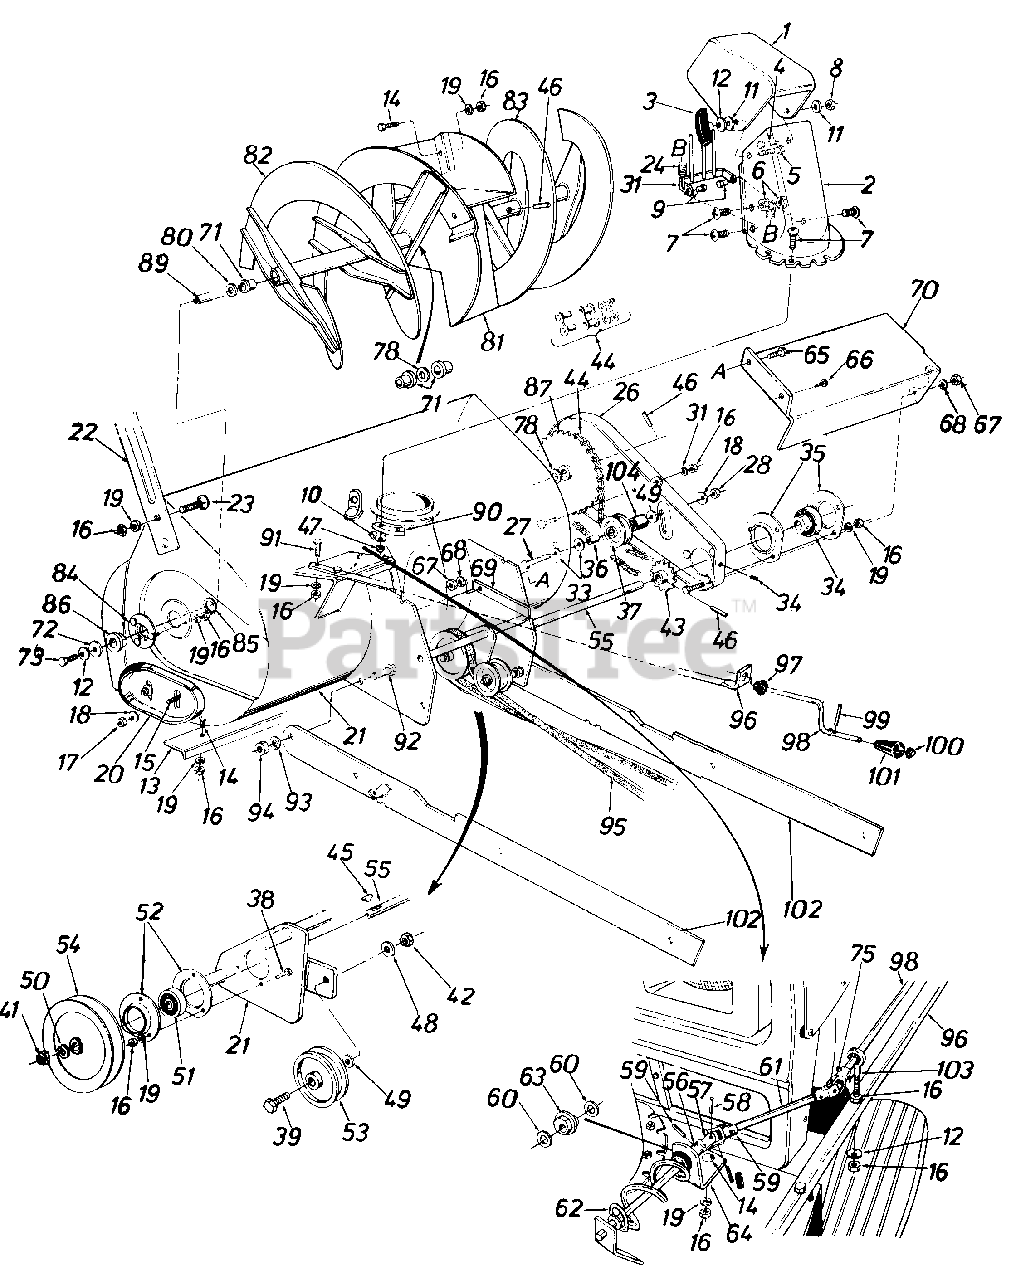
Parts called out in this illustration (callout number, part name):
1	Upper Chute
2	Lower Chute
3	Knob Handle Ass'y.
4	Truss Mach. Scr. 5/16-18 x .75" 4.
5	Carriage Bolt 5/16-18 x 1.0"*
6	Hex Cent. L-Nut 5/16-18 Thd.
7	Truss Mach. Scr. 1/4-20 x .75" 4.
8	Hex Cent. L-Nut 5/16-18 Thd.
9	Shld. Nut 1/4-20 Thd.
10	Fl.-Wash. 1/4" I.D.
11	Fl.-Wash. .344" I.D. x 1.125"
12	Bell. Wash. .345" I.D. x .88"
14	Carriage Bolt 5/16-18 x .62"
15	Carriage Bolt 3/8-16 x .62"*
16	Hex Nut 5/16-18 Thd.*
17	Hex Jam Nut 3/8-16 Thd.
18	Bell. Wash. .40 I.D. x .88"
19	L.-Wash. 5/16" I.D.*
20	Slide Shoe
21	Spiral Hsg. Ass'y.-36"
22	Guide Blade
23	Carriage Bolt 5/16-18 x .62"*
24	Extension Spring
26	Chain Guard Ass'y.
27	Hex Bolt 3/8-16 x 2.00 4.*
28	Hex Inst.-Nut 3/8-16 Thd.
33	Fl.-Wash. .385" I.D. x .87" O.D.
34	Ball Brg. .75" I.D.
35	Flangette
36	Spacer .375" I.D. x .60" O.D.
37	Fl.-ldlere w/Flanges 1.875
38	Hex Sems Bolt 5/18 x .75" Lg.
39	Hex Bolt 3/8-16 x 1.75" 4.*
41	Hex Jam Nut 3/4-10 Thd.
42	Hex Jam Nut 3/8-16 Thd.
43	Sprocket Ass'y. 14 Teeth
44	#420 Chain x 1/2" Pitch 77 Links
45	#61 Hi-Pro-Key 3/16 x 5/8"
46	Spring Pin Spir. 5/16" Dia. x 1.75" 4
47	Hex L-Nut 1/4-20 Thd.
48	L.-Wash. 3/8" I.D.*
49	Fl.-Wash. .406" I.D. x 1.25"
50	Spring L.-Wash. 3/4" I.D.
51	Self-Aligning Brg.
52	Flangette
53	Ider Pulley
54	5/8 V-Pulley .75" I.D. x 6"
55	Drive Shaft Ass'y. - N
56	Joint Brkt. Ass'y.
57	Joint Block
58	Oval Head Rivet
59	Spiral Pin 1/8" Dia.
60	Fl.-Wash. .385" I.D. x .62"
61	Chute Crank Ext. Rod
62	Chute Crank Ass'y. R.H.
63	Plastic Bushing .380" I.D.
64	Chute Crank Brkt.
65	Hex Bolt 1/4-20 x .62" Lg.*
66	Hex Wash. S-Tap Scr. 1/4-20 x .50" 4
67	Hex Nut 1/4-20 Thd.*
68	L.-Wash. 1/4" I.D.*
69	Belt Cover
70	Drive Shaft Cover
71	Plastic Bushing
72	Washer .39" I.D. x 1.75" O.D.
73	Hex Bolt 5/16-18 x .88" Spec.
75	Cotter Pin 3/32" Dia.
78	Fl.-Wash. 1.03" I.D. x 1.62"
80	Fl.-Wash. 1.0" x 1.75"
85	Snap Ring for 1.50" Shaft
86	Flange Brg. w/flats 1.00" I.D.
87	Sprocket Hub Ass'y. 40 Teeth
89	Spiral Axle
90	Chute Flange Keeper
91	Hex Bolt 5/16-18 x 1.5" 4.*
92	Hex Bolt 1/2-13 x 1.25" 4.*
93	L.-Wash. 1/2" I.D.}
94	Hex Nut 1/2"-13 Thd.*
95	"V"-Belt
98	Chute Crank 34.5" 4.
99	Roll Pin .12 Dia. x .63
100	Push Nut 3/8" Rod
101	Knob Black
102	Linkage Arm
103	Eye Bolt 5/16-18 x 3.0" 4.
104	Idler Spacer
